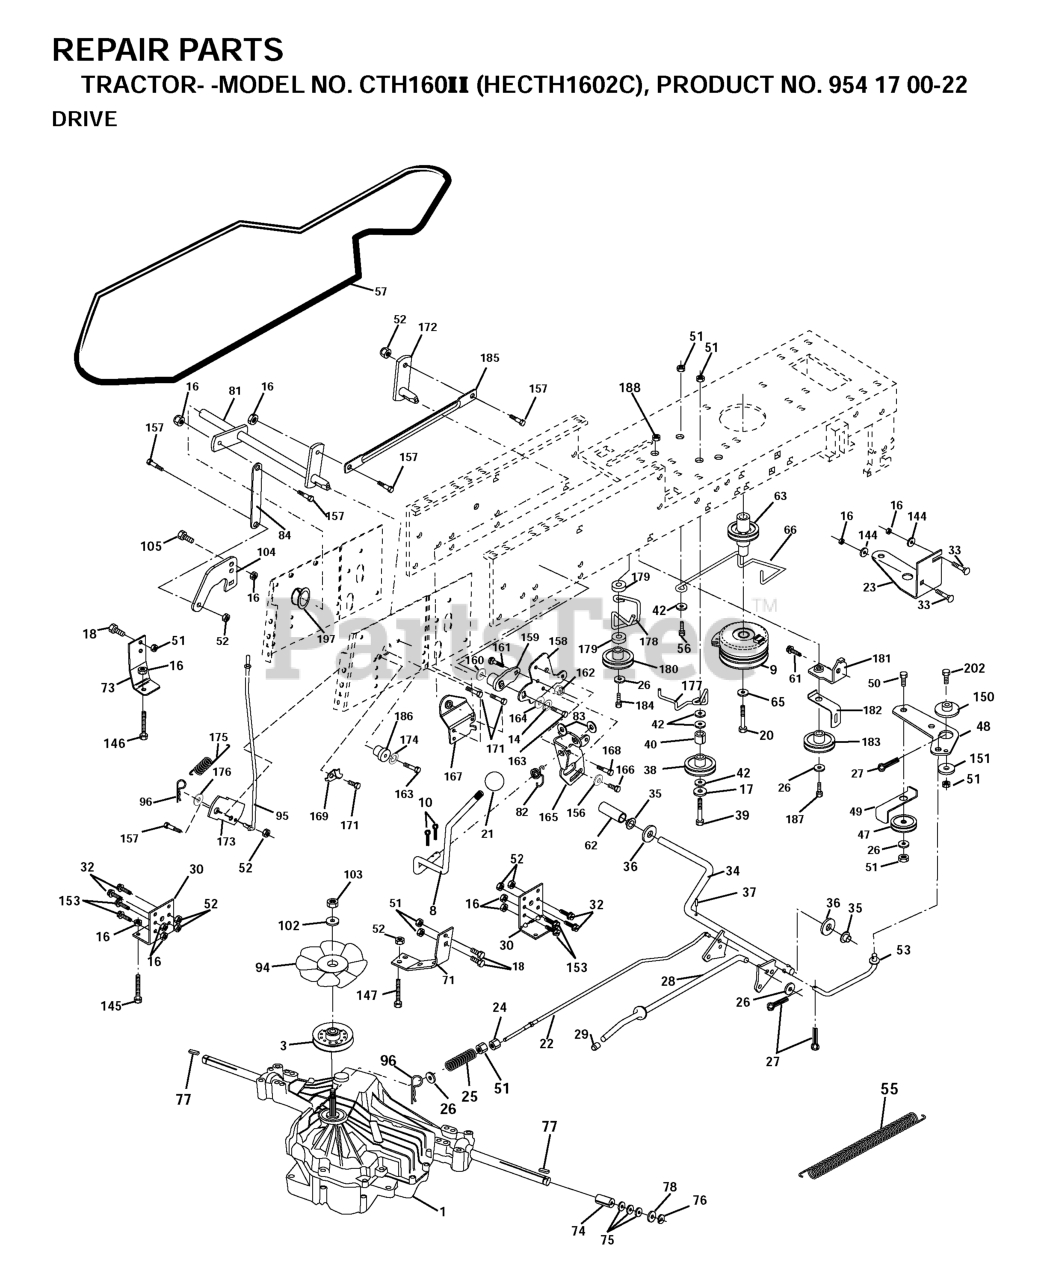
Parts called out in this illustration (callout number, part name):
3	PULLEY, TRANSAXLE
8	ROD.SHIFT.FENDER.ADJ.LT.CRD
10	PIN COTTER
14	LOCKWASHER
16	NUT.71038.31-18.HEX.NYLOCK
20	BOLT HEX
21	KNOB.DUCKHEAD.1/2
23	BRACKET.ASM.CLUTCH
24	NUT
25	SPRING ROD LT
26	WASHER
27	COTTER PIN
28	ROD BRAKE PARK LT
29	PLUNGER CAP
30	BRKT, TRNSXLE MNT 20"
32	BOLT
33	RP BOLT 5/16-18 X3/4 ZN/YEL GR
35	BEARING.NYLON
37	DRIVE PIN
38	PULLEY.FLAT
42	WASHER
47	IDLER PULLEY
48	BELLCRANK, CLUTCH
49	RETAIN BELT
50	BOLT
52	LOCKNUT
53	LINK, CLUTCH LT
55	SPRING, RETURN LT
57	V-BELT.0650.CRD.TRACTOR
61	SCREW 3/8-16X3/4
62	COVER, PEDAL (1 2)
63	PULLEY, CLUTCH ELECT EVX
65	LOCKWASHER
66	KEEPER BELT ENGINE
71	STRAP LH TORQUE
73	STRAP TORQUE RH HYDRO
74	SPACER SPLIT
77	SQUARE KEY
82	SPRING,TORSION
83	WASHER
84	LINK TRANSAXLE
94	FAN 7" HYDRO
95	BYPASS CONTROL ASM
96	RETAINER M
103	NUT.HEX.1/2-20
104	CONTROL ARM
144	Washer 11/32 x 5/8 x 16 Ga SD
146	Bolt Hex Flanged 5/16-18 Unc x 2
147	Bolt Hex Flanged 5/16-18 Unc x 2
150	BUSHING.BELLCRANK.GRD.DR
151	WASHER 12/32X2X10GA
153	BOLT RB
156	WASHER.SRRTD.5/16
157	BOLT SHOULDER 5/16-18
158	BRACKET
159	HUB
160	Washer 29/32 x 1 - 1/4 x 16 Ga.
161	BOLT
162	NUT.CROWNLOCK.1/4
164	Washer 5/8 x .281 x 10 Ga.
165	RP BRACKET
167	BRACKET.SUPT.SHIFT.CRD
168	BOLT.SHOULDER.5/16-18X
169	PLATE.FASTENING.CROSS.SHAFT
174	LOCKWASHER
175	SPRING.BYPASS.CRD
176	Washer 7/32 x 1/2 x 16 Gauge
180	PULLEY.FLAT.IDLER
181	BRKT.IDLER.GRD.DR.CRD
182	KEEPER BELT
183	PULLEY.V-IDLER
184	SCREW.HXWSH.3/8
186	HUB.TAPERED.ROUND.CRD
187	SCREW
188	SNAP BUSHING T
197	NYLINER SNAP 5/8" ID
202	BOLT.3/8-16X1.50
